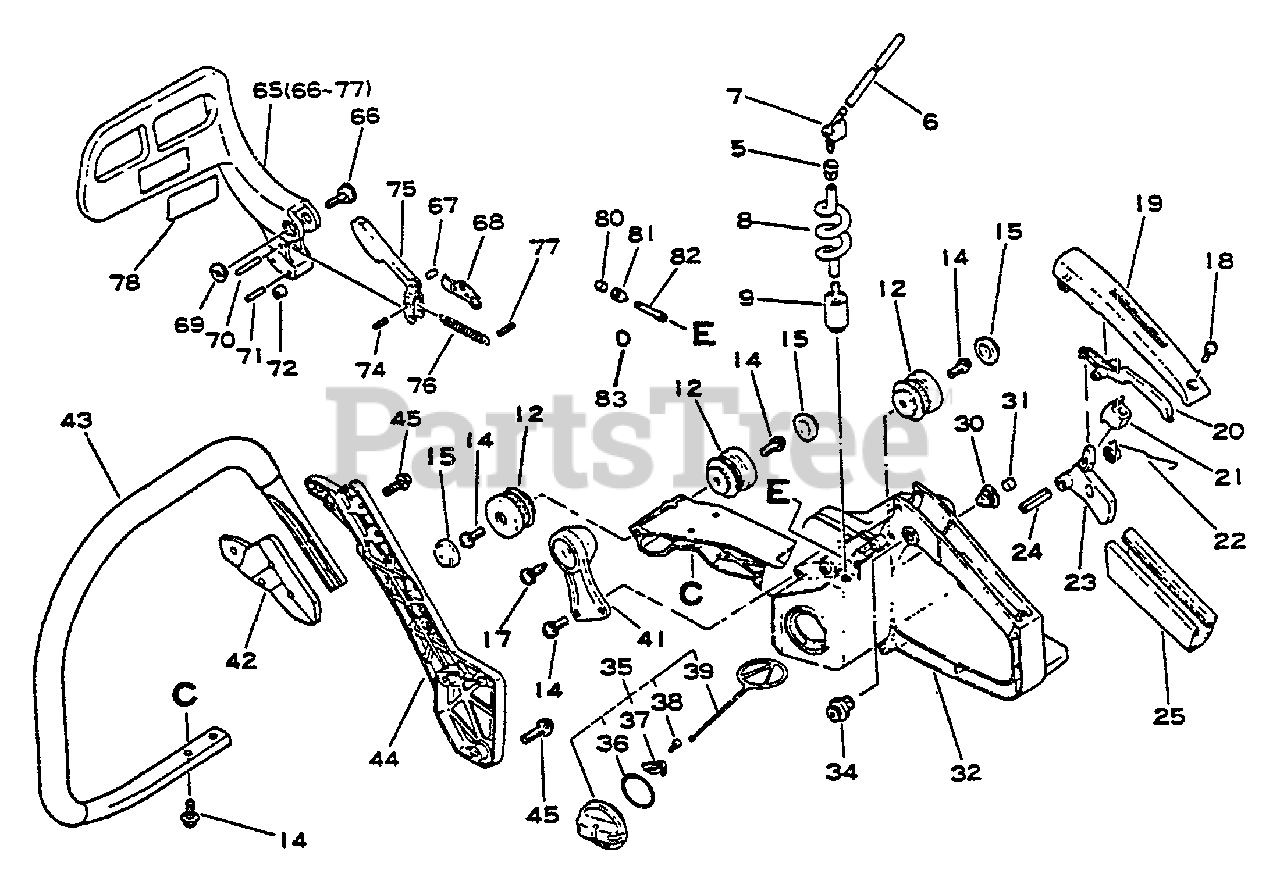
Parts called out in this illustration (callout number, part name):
5	GROMMET
6	PIPE - 3X6X100 -- BLACK
7	CONNECTOR, PIPE
8	PIPE - BLACK
9	FILTER, FUEL
14	SCREW - 5X14
15	CAP, CUSHION
17	SCREW - 5X14
18	SCREW - 4X14
19	COVER, HANDLE
20	LEVER, TRIGGER LOCKOUT
22	SPRING, TRIGGER
23	TRIGGER, THROTTLE
24	PIN - SPRING -- 5X25
25	GRIP, HANDLE
32	HANDLE - REAR
34	LATCH, THROTTLE
35	CAP ASSY
36	O-RING - 29
37	RETAINER
38	SCREW - 3X8
39	CONNECTOR, CAP
42	BRACKET, HANDLE - INNER
43	HANDLE - FRONT
44	BRACKET, HANDLE - OUTER
45	SCREW - 5X20
65	BRAKE LEVER ASSY
67	PIN - SPRING -- 4X8
68	STOPPER
70	PIN - 3X24
72	SPACER
74	PIN - SPRING -- 3X12
75	WEIGHT, BRAKE
76	SPRING, RETURN
77	PIN - SPRING -- 3X16
80	VENT, FUEL TANK
81	COVER, VENT
82	PIPE - VENT
83	CLIP - 5.5
